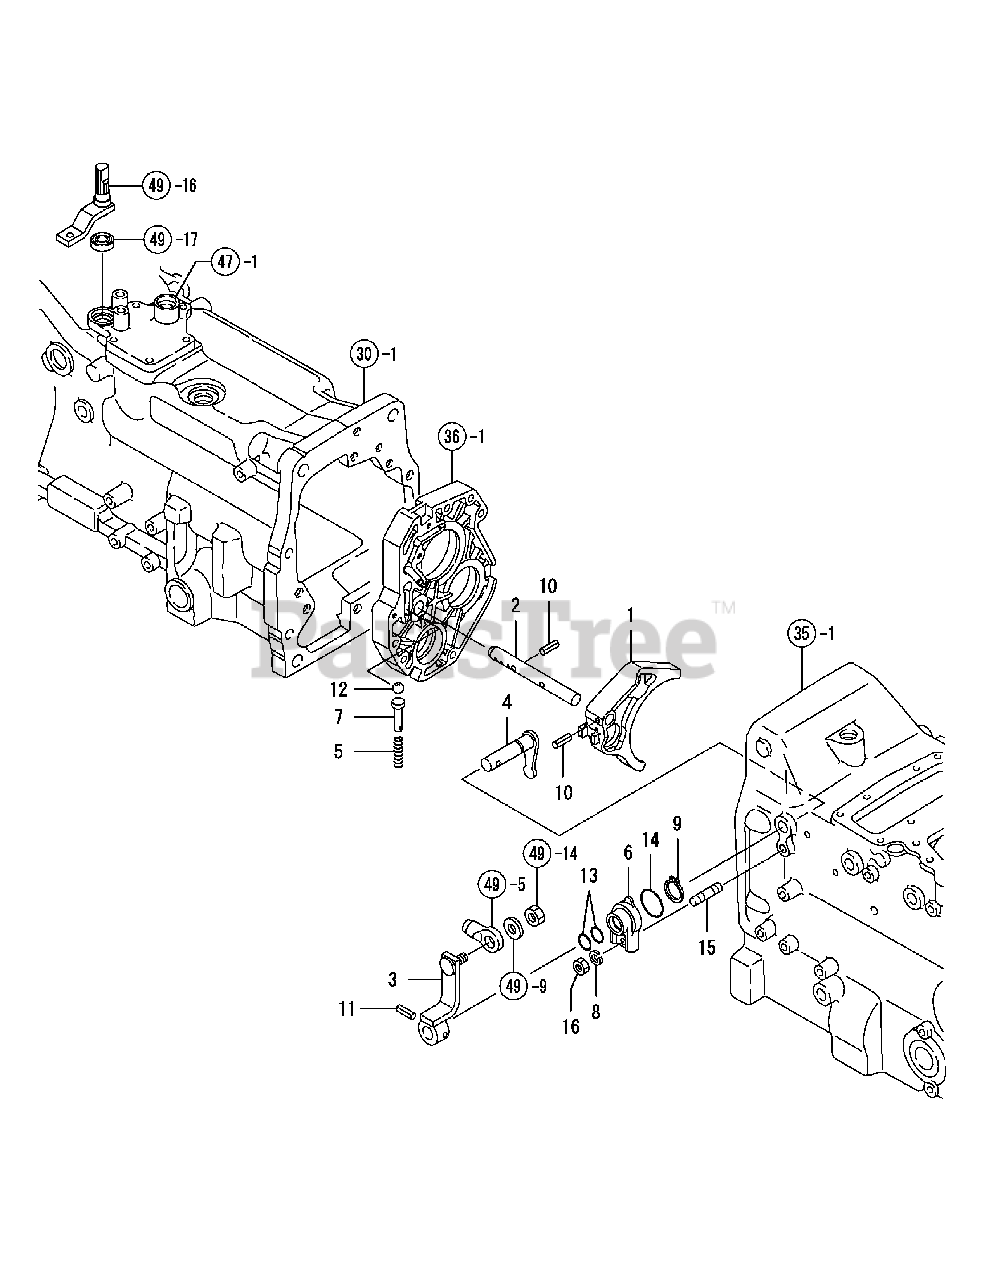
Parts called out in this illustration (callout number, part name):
1	SHIFT FORK,REVERSER
2	SHAFT,REVERSER FORK
3	ARM,REVERSER CHAIN
4	ARM,REVERSER SHIFT
7	PIN 4X35,FLAT HEAD.
10	SPRING PIN 6X25
11	SPRING PIN 6X32
12	BALL 5/16, STEEL
13	O-RING 1A P-16.0
14	O-RING 1A G-25.0
